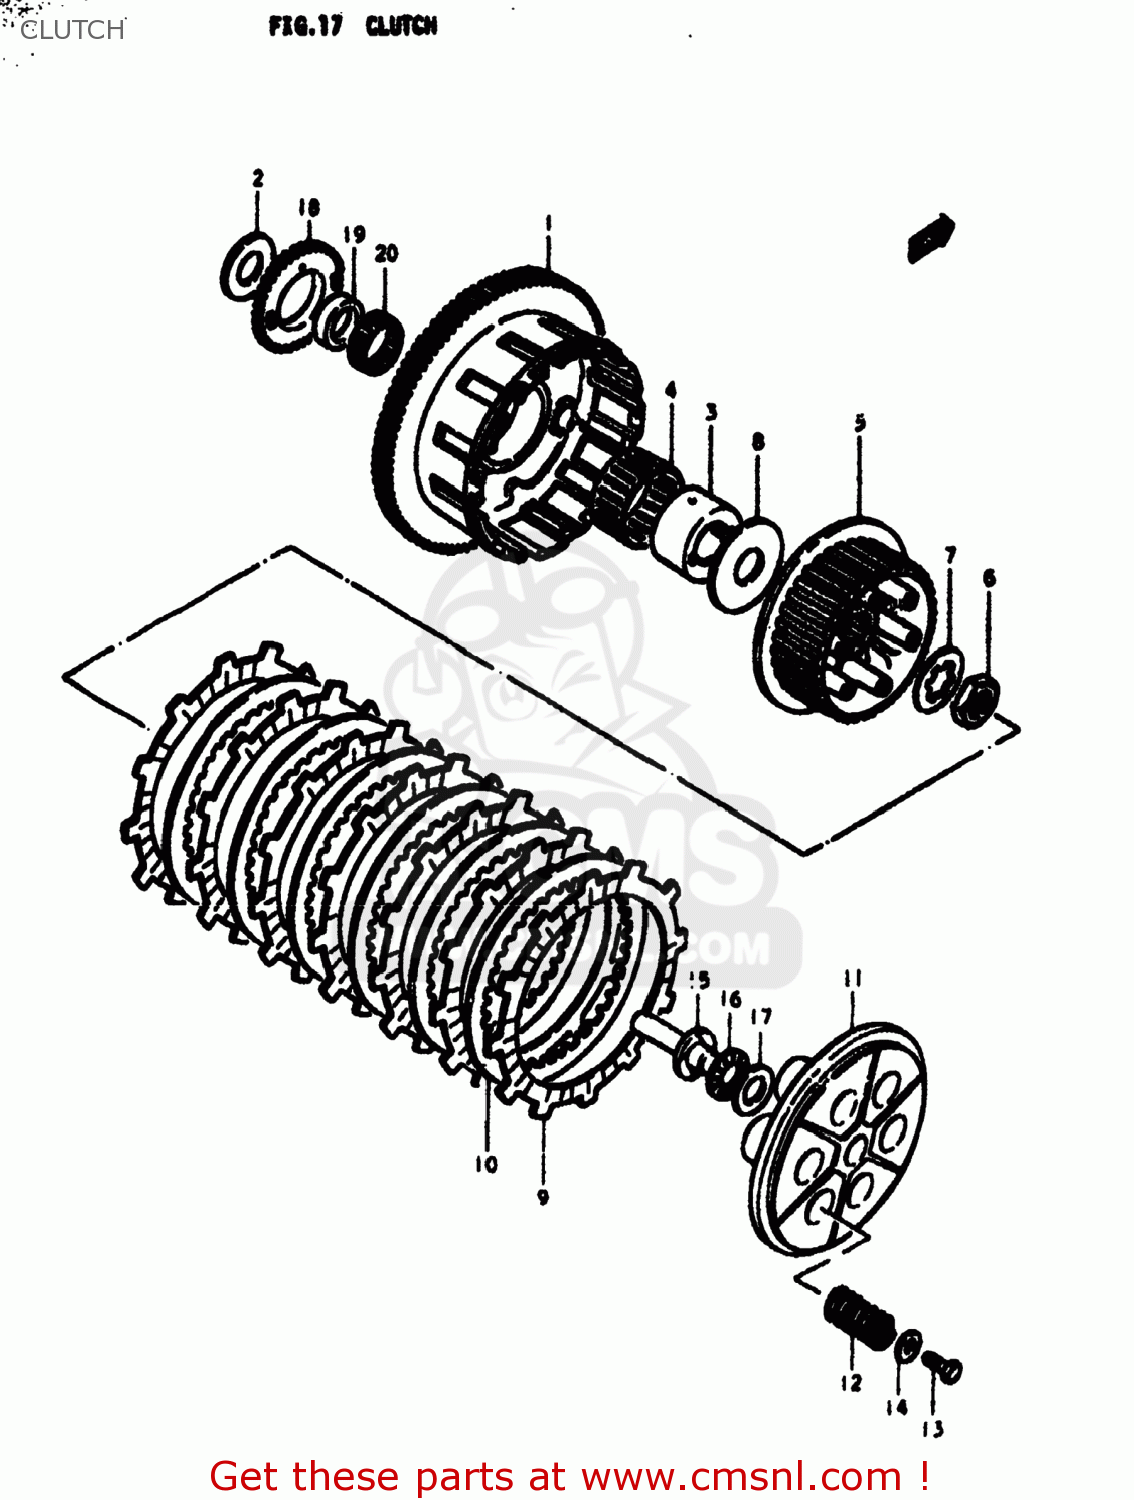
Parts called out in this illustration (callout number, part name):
1	GEAR ASSEMBLY,PRIMARY DRIVE
2	WASHER
3	SPACER,PRIMARY DRIVEN
4	BEARING
5	HUB,CLUTCH SLEEVE
6	NUT
7	WASHER,LOCK
8	WASHER(25X66X3.5)
9	PLATE,CLUTCH DRIVE (NAS)
10	PLATE,CLUTCH DRIVEN (NAS)
11	DISC,CLUTCH PRESSURE
12	SPRING
13	BOLT, UPPER
14	WASHER
15	PIECE,CLUTCH PUSH
16	BEARING(15X28X2)
17	WASHER
18	GEAR,OIL PUMP DRIVE
19	SPACER,OIL PUMP DRIVE GEAR
20	BEARING(36X40X10)
